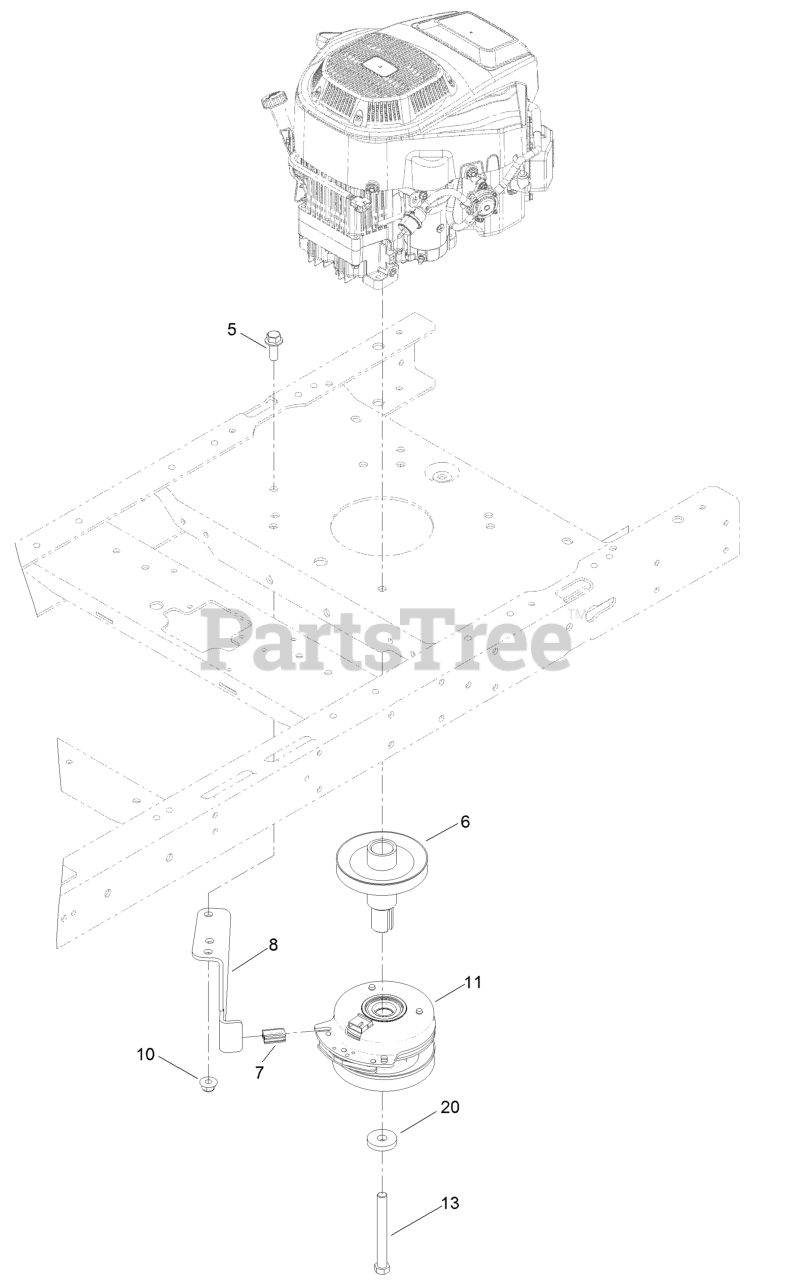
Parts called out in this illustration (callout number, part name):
5	SCREW-HHF 3/8-16 X 1
6	PULLEY-ENGINE
7	ISOLATOR-CLUTCH
8	STOP-CLUTCH
10	NUT-HF, NI
11	CLUTCH-PTO
13	SCREW-HH
20	WASHER
